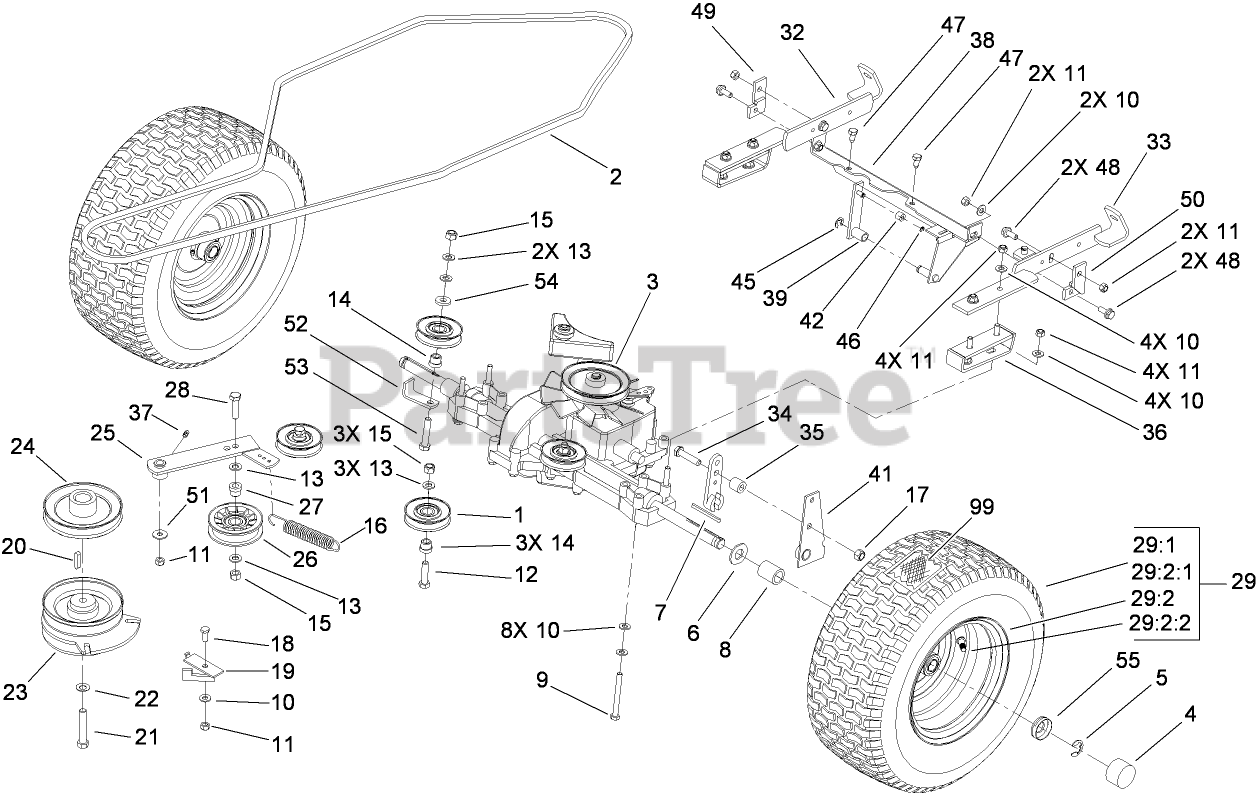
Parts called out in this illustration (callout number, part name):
1	PULLEY-IDLER
2	V-BELT-TRACTION
3	TRANSMISSION
4	CAP-HUB
5	CLIP-SPRING
6	WASHER
7	KEY-SQUARE
8	SPACER-AXLE
9	SCREW-HH
10	WASHER-PLAIN
11	NUT-LOCK, NI
12	SCREW-HH
13	WASHER-FLAT
14	BUSHING-IDLER
15	NUT-LOCK, NI
16	SPRING
17	NUT-LOCK, NI
18	SCREW-HH
19	RETAINER
20	KEY-SQUARE
21	SCREW-HH
22	WASHER-SPRING, BELLEVILLE
23	CLUTCH-ELECTRIC
24	PULLEY-ENGINE
25	ARM-IDLER
26	PULLEY-IDLER
27	BUSHING-IDLER
28	SCREW-HH
29	Loose Parts Package
29:1	TIRE
29:2	WHEEL ASM
29:2:1	Loose Parts Package
29:2:2	Valve-Tire
32	Bracket-Right
33	Bracket-Left
34	SCREW-HH
35	SLEEVE
36	BRACKET-SUPPORT
37	FITTING-GREASE
38	Bar ASM
42	Roller
45	Stirrup
46	STIRRUP
47	SCREW-THREAD FORMING
48	SCREW-HEX
49	BRACKET-RIGHT
50	BRACKET-LEFT
51	WASHER-PLAIN
52	RETAINER-BELT
53	SCREW-HH
54	WASHER-FLAT
55	RETAINER-CAP, HUB
